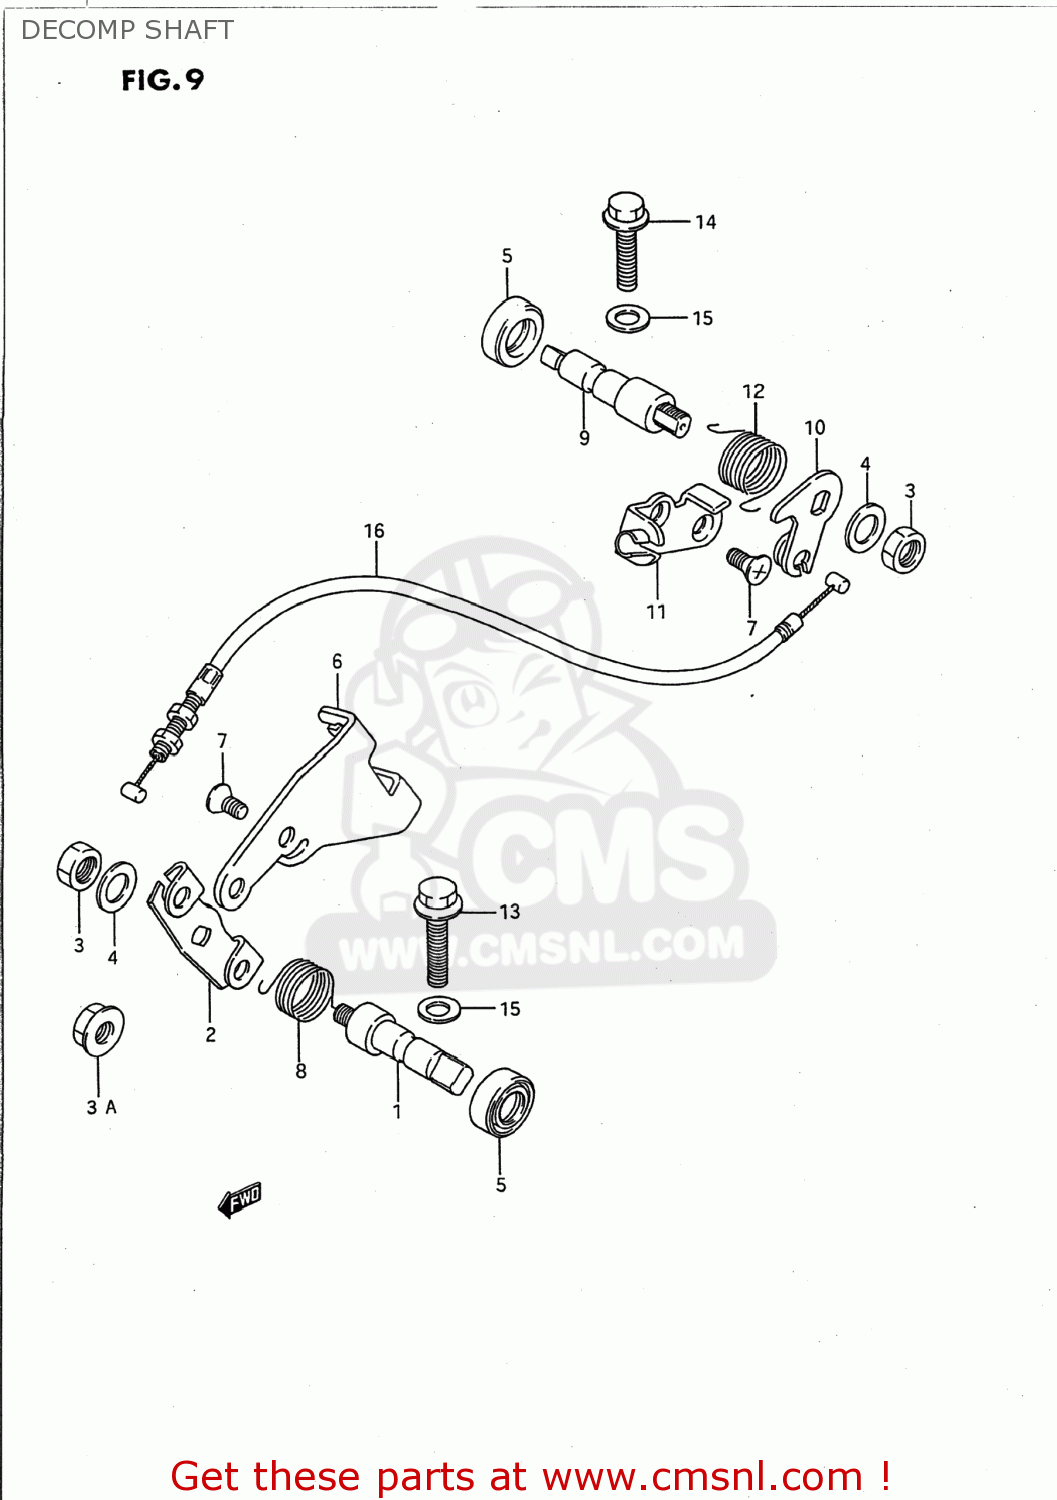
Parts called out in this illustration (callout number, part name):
1	SHAFT,DECOMP FR
2	LEVER,DECOMP SHAFT FR
3	NUT
3A	NUT
4	WASHER
5	SEAL,OIL(10X20X6)
6	HOLDER,DECOMP CABLE FR
7	SCREW
8	SPRING
9	SHAFT,DECOMP RR
10	LEVER,DECOMP SHAFT RR
11	HOLDER,DECOMP CABLE RR
12	SPRING
13	BOLT
14	BOLT
15	GASKET(5.8X13X1.2) (NAS)
16	CABLE ASSEMBLY,DECOMPRESSION
